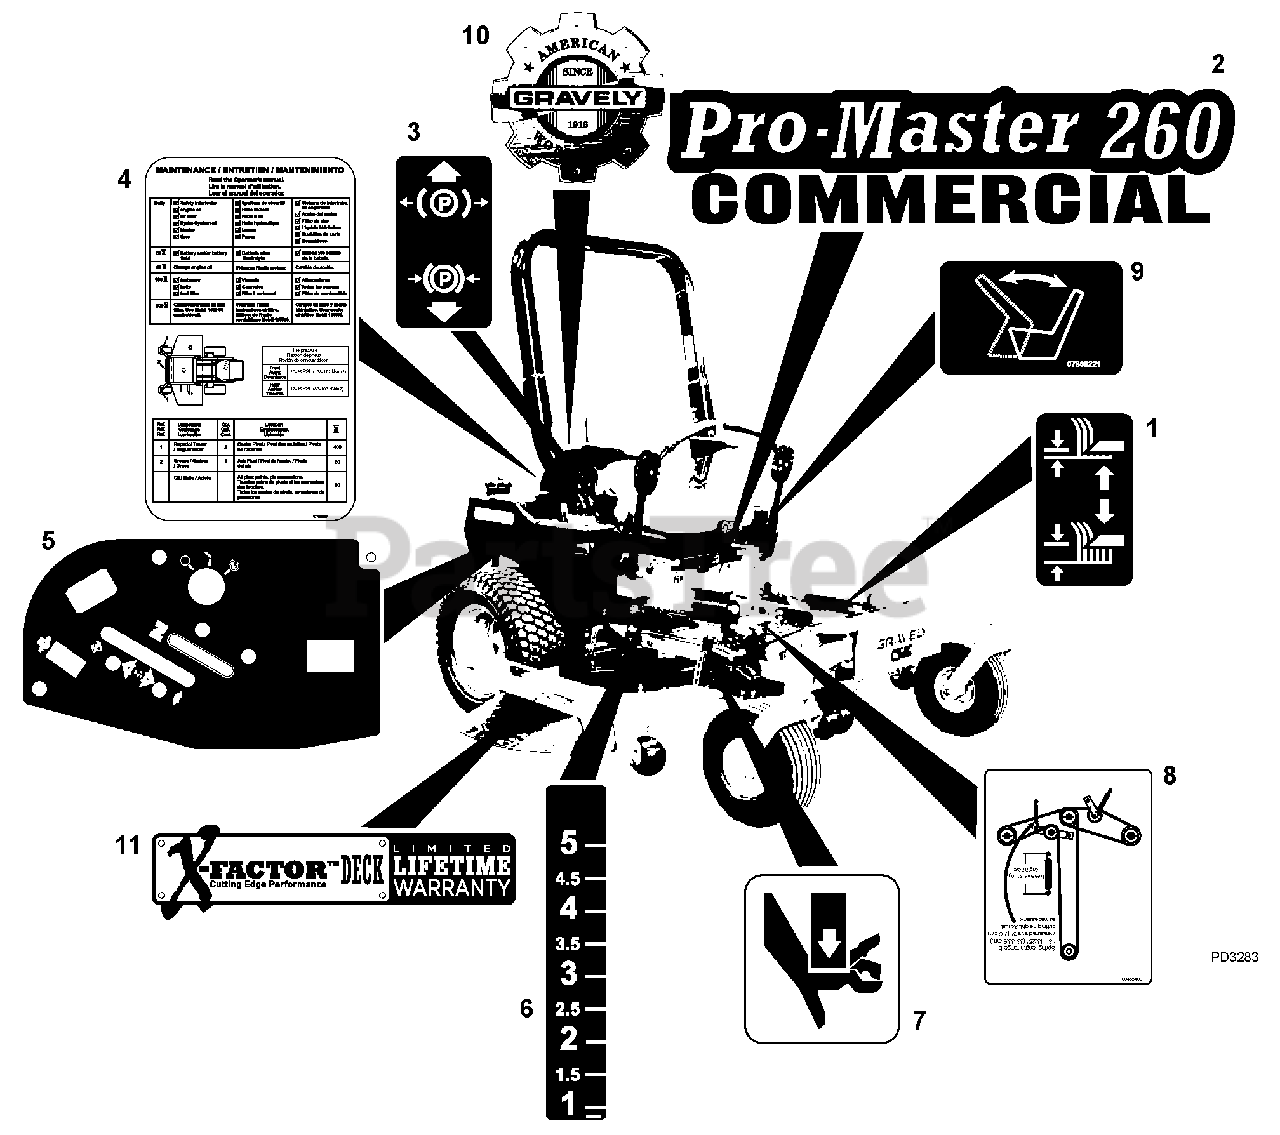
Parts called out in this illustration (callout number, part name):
1	Decal, Lift Lever
2	Decal, Pro-Master 260
3	Decal, Parking Brake Lever
4	Decal, Maintenance Instructions
5	Decal, Control Panel
6	Decal, Height of Cut
7	Decal, Pinch Point
8	Decal, Belt Diagram (992217)
9	Decal, Seat Release
10	Decal, Heritage Large
11	Decal, X-Factor Deck
